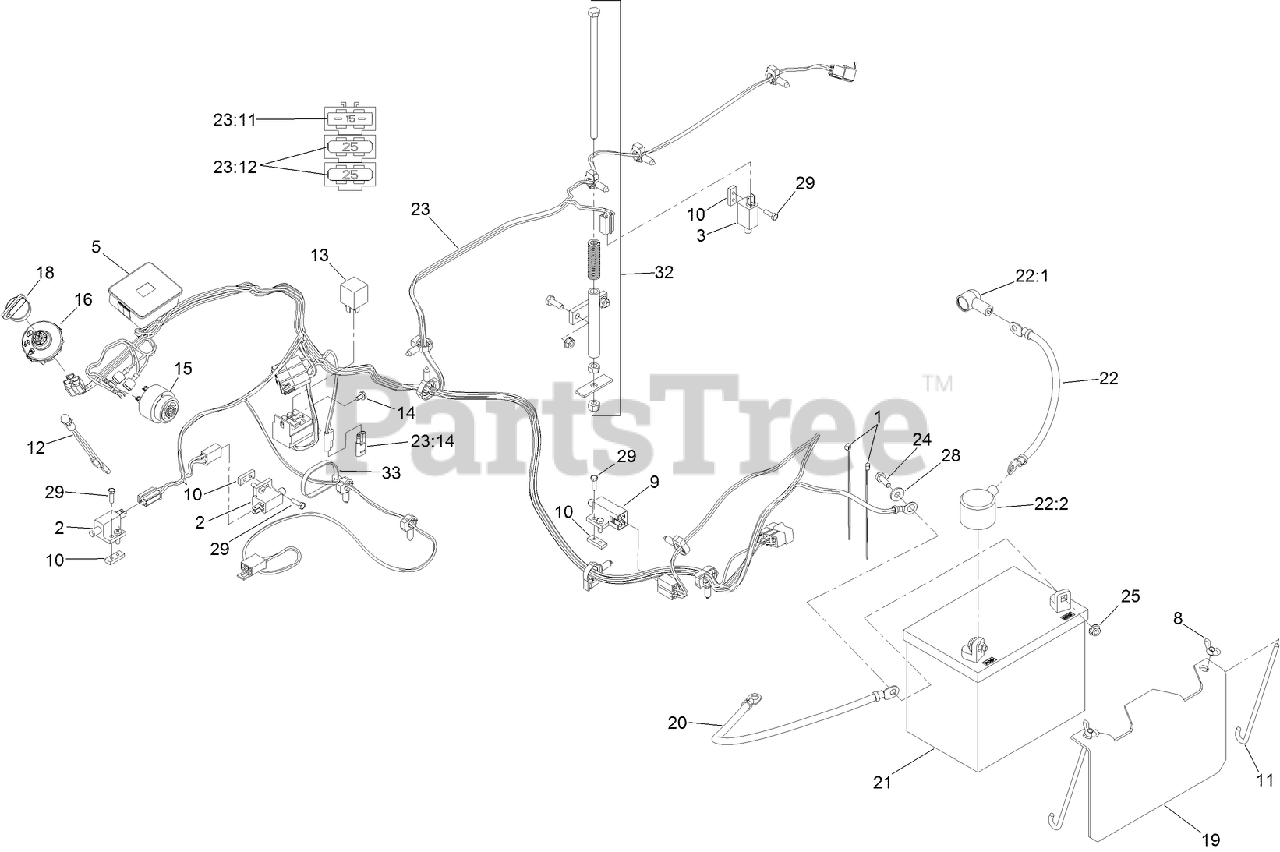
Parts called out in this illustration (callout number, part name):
1	TIE-CABLE
2	SWITCH-OPEN, NORMALLY
3	SWITCH-CLOSED, NORMALLY
5	HOUR METER ASM
8	WINGNUT
9	SWITCH
10	PLATE-TAPPED
11	BOLT-HOLDDOWN
12	INDICATOR-LED, RED
14	SCREW-HWH
15	ALARM-TONE, DUAL
16	SWITCH-IGNITION
18	KEY-IGNITION
19	HOLD DOWN-BATTERY
20	CABLE-BATTERY, NEGATIVE
21	BATTERY (300 CCA, WET)
22	CABLE-BATTERY, POSITIVE
22:1	INSULATOR-SOLENOID
22:2	INSULATOR-BATTERY
23	HARNESS-WIRING
23:11	FUSE-BLADE, 15 AMP
23:12	FUSE-BLADE, 25 AMP
23:14	CAP-PLUG
24	SCREW-HH
25	NUT-HF
28	WASHER-FLAT
32	HOPPER SWITCH ACTUATOR ASM
33	TIE-PLASTIC
